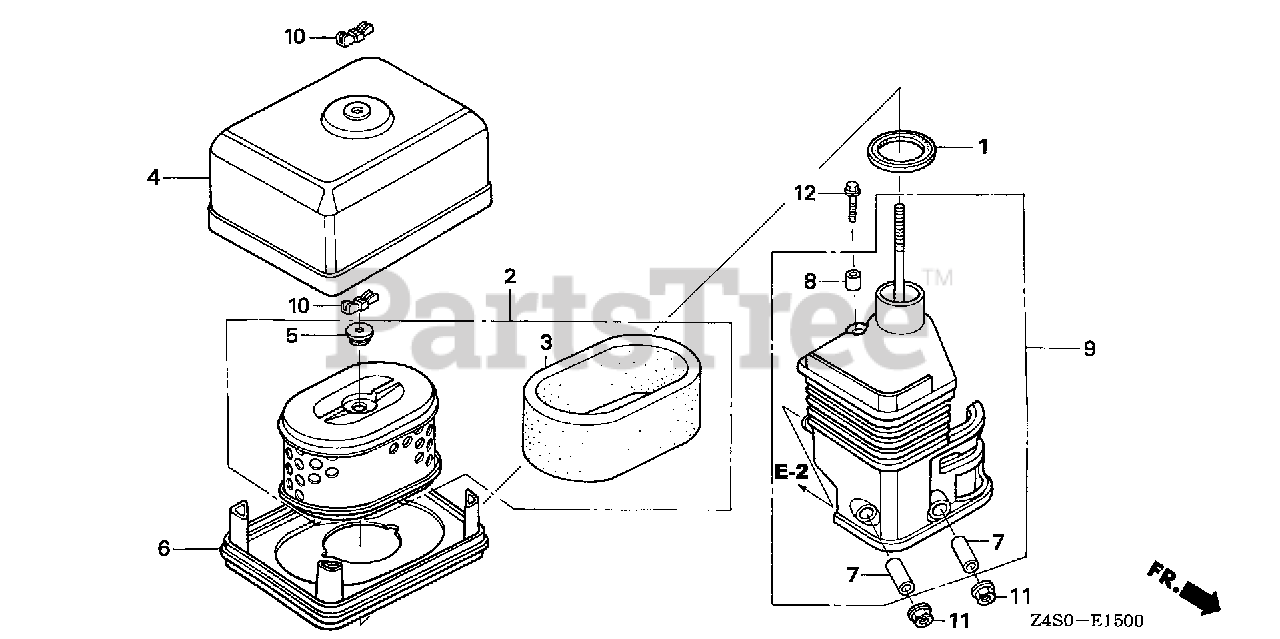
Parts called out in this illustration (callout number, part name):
1	GASKET, ELBOW
2	ELEMENT, AIR CLEANER (DUAL) Use up to Engine SN 2115700.
2	ELEMENT, AIR CLEANER (DUAL)
3	FILTER (OUTER)
4	COVER, AIR CLEANER (DUAL)
5	GROMMET, AIR CLEANER
6	NOSE, MUFFLER
7	COLLAR, AIR CLEANER Use from Engine SN 1786085.
8	COLLAR B, AIR CLEANER
9	ELBOW, AIR CLEANER Use from Engine SN 1786085.
10	WINGNUT, TOOL BOX SETTING
11	NUT, FLANGE (6MM)
12	BOLT, FLANGE (6X20)
